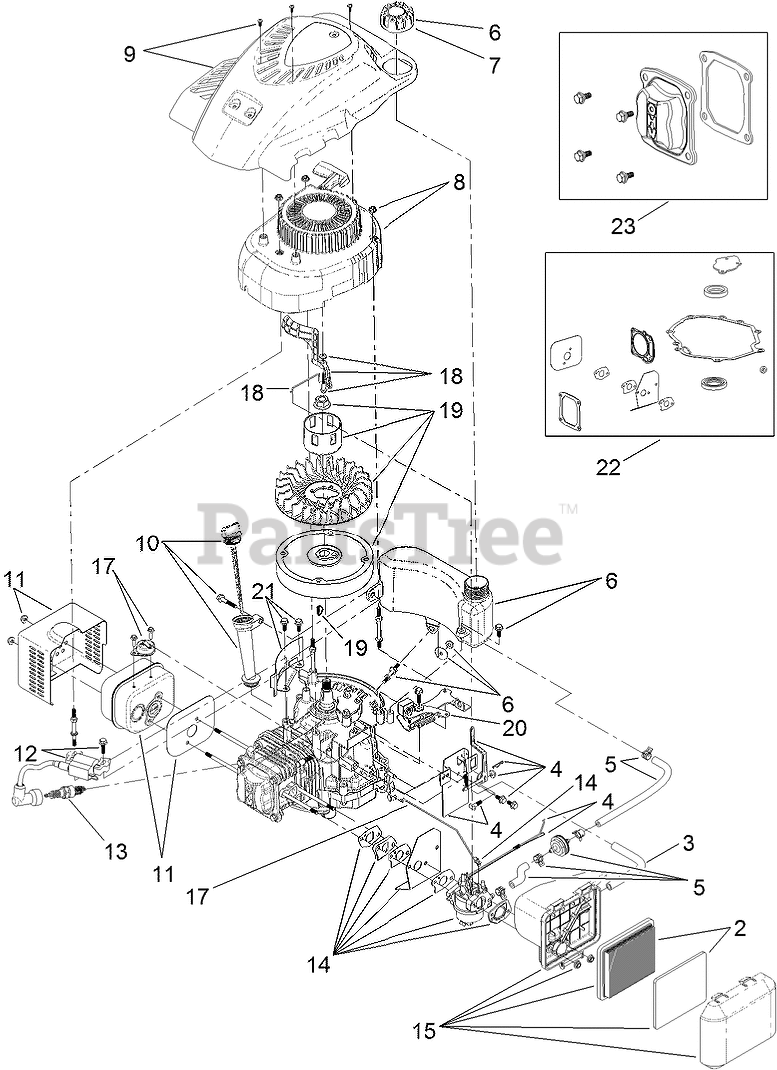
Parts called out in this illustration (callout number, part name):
2	AIR FILTER AND PREFILTER KIT
3	TUBE-BREATHER
4	GOVERNOR ARM KIT
5	FUEL LINE KIT
6	FUEL TANK KIT (CAP AND HARDWARE)
7	CAP-FUEL
8	SHROUD AND RECOIL ASM
9	Shroud ASM
10	DIPSTICK AND FILL TUBE KIT
11	MUFFLER AND SHIELD KIT
12	IGNITION AND HARDWARE KIT
13	PLUG-SPARK
14	CARBURETOR REPAIR KIT
14	CARBURETOR COMPLETE KIT
15	AIR CLEANER ASM
17	THERMAL CHOKE CONTROL KIT
18	AIR VANE CHOKE KIT
19	FLYWHEEL AND FAN KIT
20	BRAKE ASM RECOIL KIT
21	FLYWHEEL SHIELD KIT
22	SEAL AND GASKET KIT
23	VALVE COVER KIT
